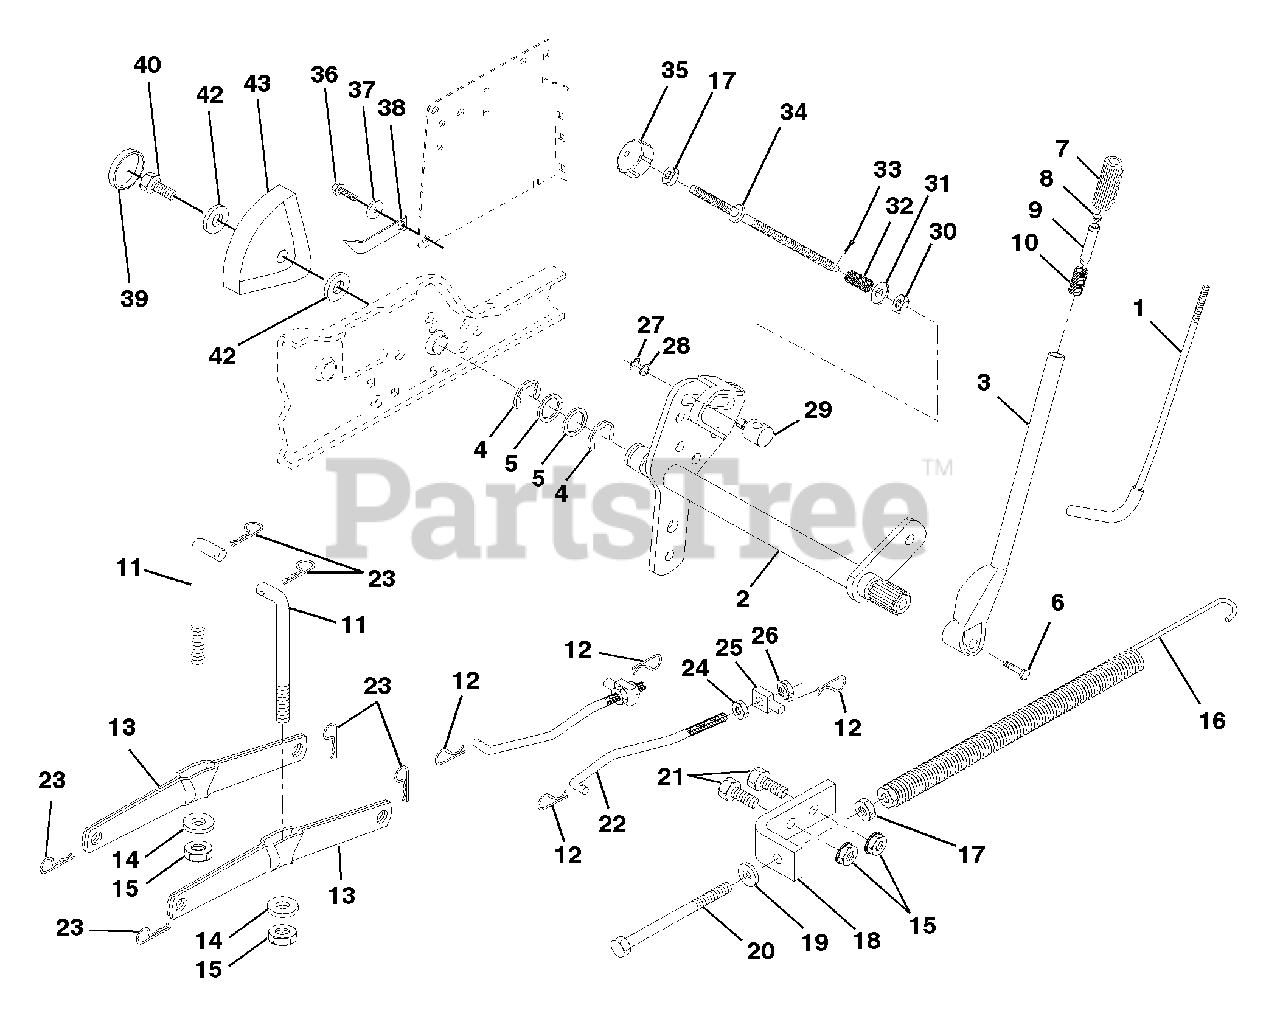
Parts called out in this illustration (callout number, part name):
1	Rod Asm., Lever
2	Shaft Asm., Lift Vgt
3	Lever Asm., Lift Rh
4	E-Ring Truarc #5133-87
5	Washer 29/32 x 1-1/4 x 16 Ga.
6	Bolt, Fin Hex 3/8-16 x 1-1/2
7	Grip, Handle Fluted
8	Button, Plunger
9	Plunger, Lever Lift
10	Spring 2-1/8"
11	Link Lift
12	Retainer, Spring
13	Arm, Suspension Vgt
14	Bearing
15	Nut, Lock Hex W/Wsh 3/8-16 Unc
16	Spring Asm., Assist Lift
17	Nut, Hex Jam 3/8-16 Unc
18	Bracket, Spring Assist
19	Washer 13/32 x 13/16 x 16 Ga.
20	Bolt, Adjust Spring Assist
21	Bolt, Fin Hex 3/8-16 x 1
22	Link, Front
23	Retainer, Spring
24	Nut, Jam Hex 1/2-13 Unc
25	Trunnion
26	Nut, Lock W/Wsh 1/2-13 Unc
27	Ring, Klip #T5304-37
28	Washer 15/32 x 3/4 x 16 Ga.
29	Trunnion, Dp Stop Dbl Thds Plt
30	Nut, Special
31	Washer 13/32 x 5/8 x 16 Ga.
32	Spring, Compression Inf Hgt
33	Pin, Cotter 3/32 x 1/2
34	Rod, Adj Lift
35	Knob, Inf 3/8-16 Unc
36	Screw, Thdrol 3/8-16 x 3/4
37	Washer, Nylon
38	Pointer, Pnt Height Indicator
39	Plug, Hole
40	Screw Thdrol. 5/16-18 x 3/4
42	Washer 11/32 x 1-1/2 x 10 Ga.
43	Scale, Indicator Height
